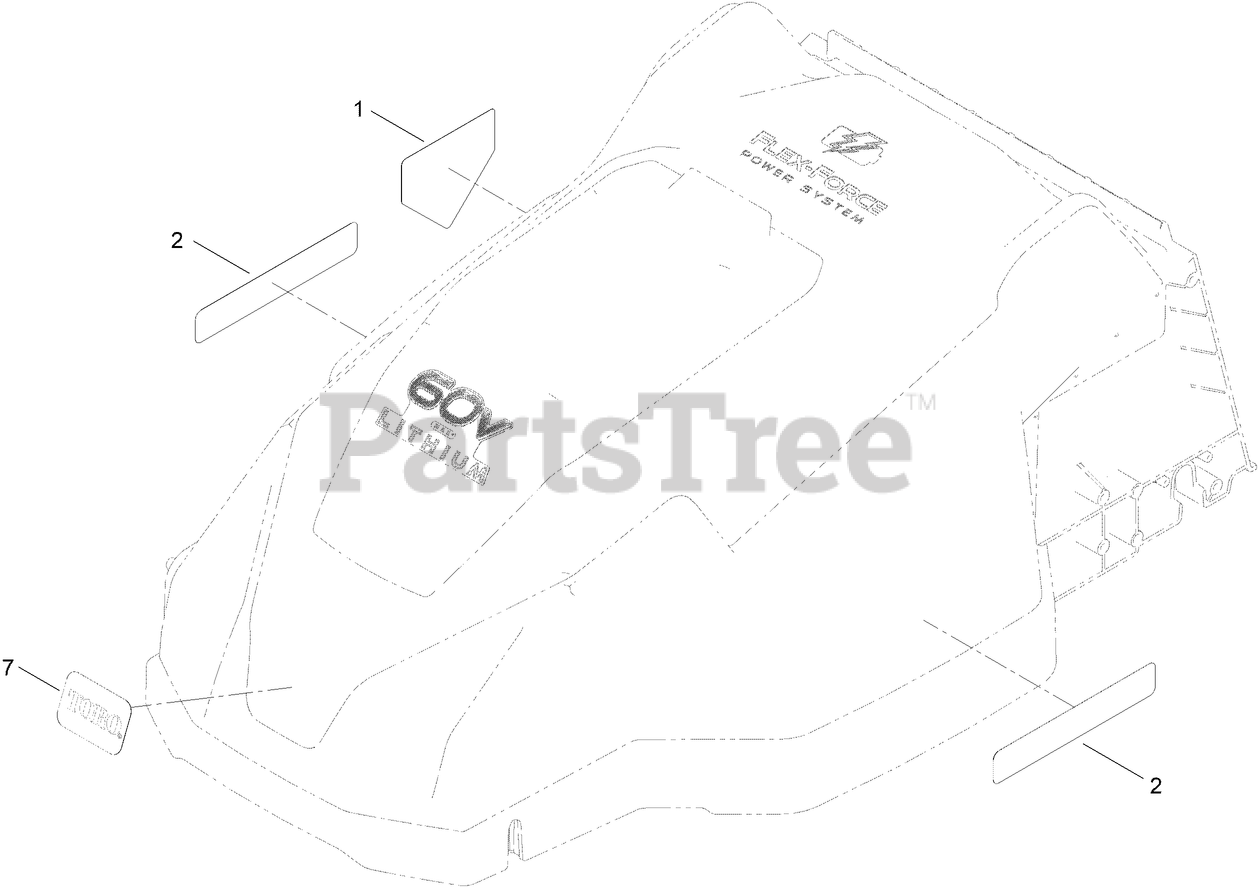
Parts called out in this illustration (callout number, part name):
1	DECAL-DANGER
2	DECAL-DECK
7	DECAL-TORO, SILVER (2.75 X 1.8)
